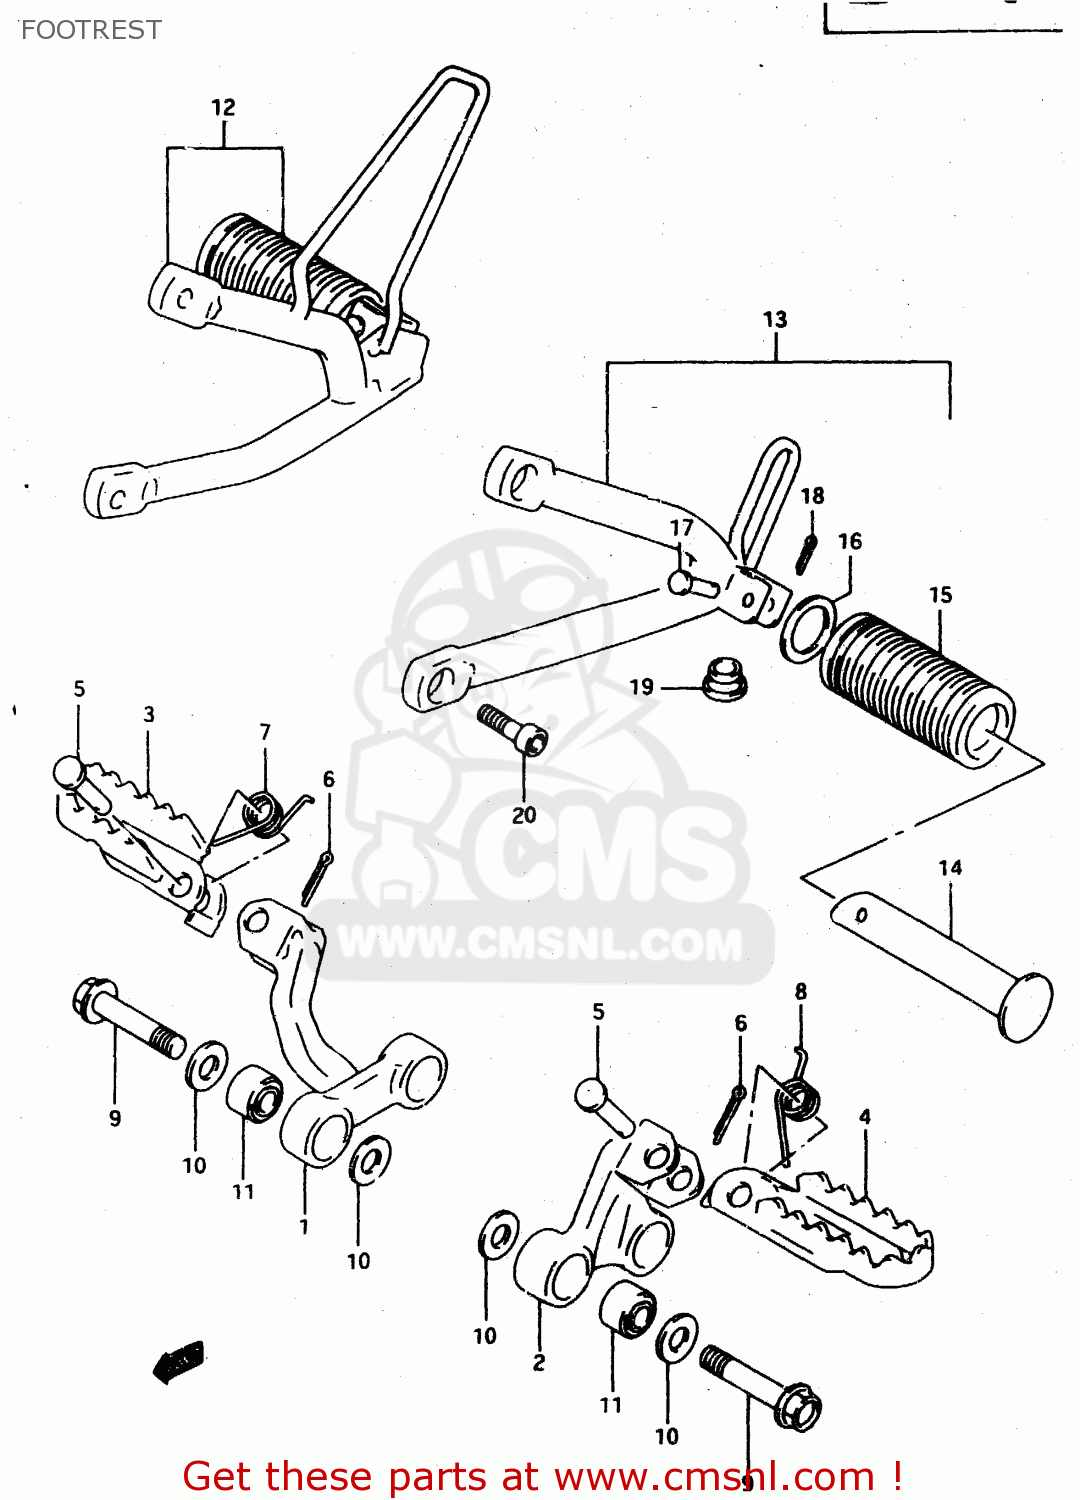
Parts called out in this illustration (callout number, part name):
1	BAR,FR FOOTREST,R
2	BRACKET,FR FOOTREST,L
3	FOOTREST,FR,R
4	FOOTREST,FR,L
5	PIN
6	PIN 20X20
7	SPRING
8	SPRING
9	BOLT(10X50)
10	WASHER
11	BUSH(10.2X25X19)
12	FOOTREST ASSEMBLY,PILLION
13	FOOTREST ASSEMBLY,PILLION
14	BAR,FOOTREST RUBBER
15	RUBBER,PILLION FOOTREST
16	WASHER (19.5X32X2)
17	PIN
18	PIN
19	CAP(OD:19)
20	BOLT
